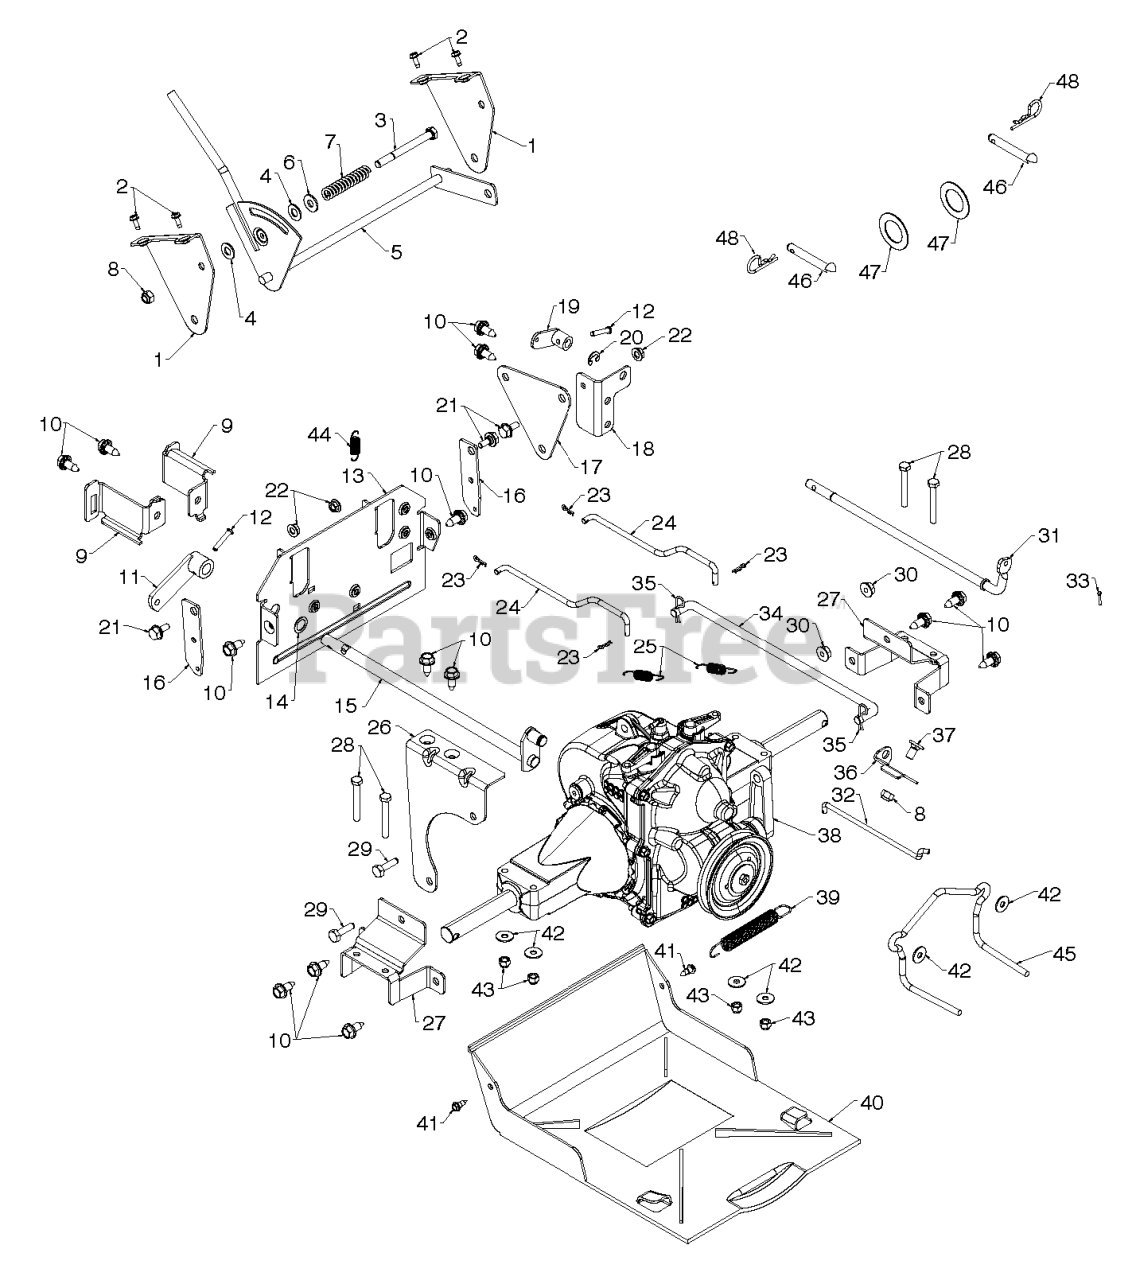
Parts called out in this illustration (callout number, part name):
1	BRACKET.SHIFT.HYDRO
3	SCREW 5/16-18 X 3.25
4	WASHER, NYLON FRICTION
5	CONTROL.WLD.HYD.II
6	WASHER.20X8.5
7	SRPING.FRICTION.HYDRO
8	NUT.71038.31-18.HEX.NYLOCK
9	BRACKET.CABLE.PNT.HYDRO
10	BOLT.HEX.HD.WASHER.5/16-18X.75
11	ARM, AUGER CONTROL
12	CLEVIS PIN
13	PLATE.REAR.HYDRO.PNT.ORANGE
14	THRUST WASHER
15	CONTROL.SHAFT.ASM
16	LEVER.STEER.CABLE.PNT.SNOW
16	BRACKET.SPEED.PIVOT.YZP
17	BRACKET.SPEED.PIVOT.YZP
18	BRACKET.SPEED.PIVOT.YZP
18	LEVER.STEER.CABLE.PNT.SNOW
19	ARM.HYD.CLUTCH
20	E-RING.RETAINER.REINFORCED.375
21	BOLT.SHOULDER.3/X.25
22	NUT.HEX.FLANGE.1/4
23	COTTER PIN (3 2)(2 2MC)
24	ROD.STEER.HYD
25	SPRING.RETURN
26	BRACKET.HYDRO.STABILIZER
27	BRACKET.TRANSMISSION.MOUNT
28	BOLT.HEX.1/4-20X2.00.HEX.HD.
29	BOLT RB
30	NUT.LOCK.5/16-18
31	SHAFT.HYD.CLUTCH
32	ROD.HYDRO CLUTCH
33	RETAINER CLIP
34	ROD.SPEED.CONT.HYD.SNOW
35	SPRING RETAINER
36	BRACKET.HYD.CLUTCH.
37	BOLT.CARRIAGE.5/16-18X
38	TRANSMISSION.HYDROII.PS
39	SPRING, BRAKE
40	PAN.BOTTOM.PLASTIC.SNOW
41	SCREW, HEX HEAD, TAPPING
42	WASHER
43	LOCKNUT.NYLOC.1/4-20
45	GUIDE BELT.HYDRO 2
46	RIVET
47	THRUST WASHER
48	RETAINER M
